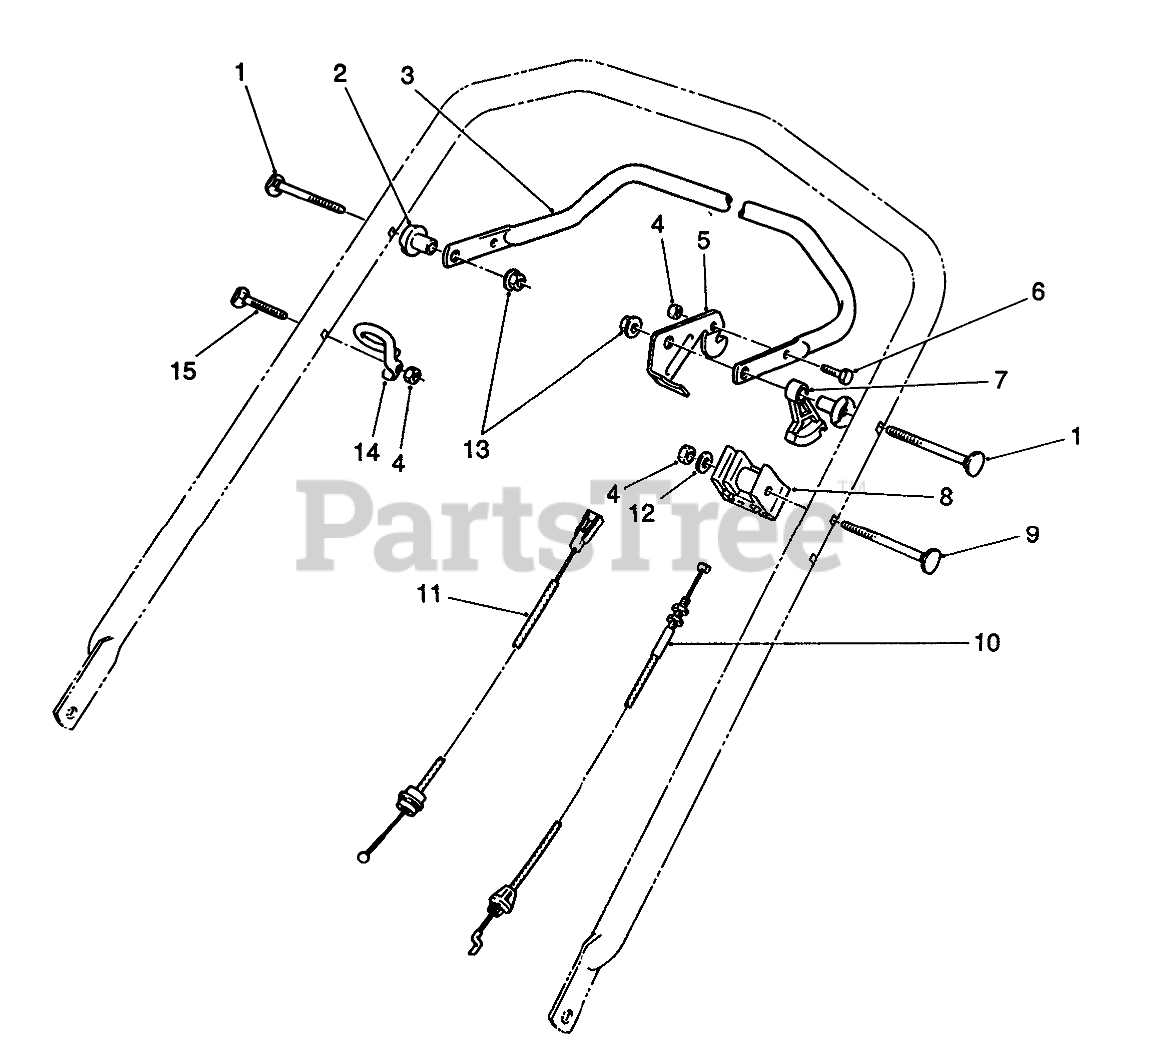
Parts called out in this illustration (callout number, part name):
1	SCREW-HANDLE
2	SPACER-SUPPORT
3	Bar-Control
4	NUT-LOCK, NI
5	LEVER-CONTROL
6	SCREW-HH
7	LEVER-TRACTION
8	SUPPORT-CABLE
9	SCREW-HANDLE
10	TRACTION CABLE
11	BRAKE CABLE
12	WASHER-FLAT
13	NUT-LOCK, NI
14	GUIDE-ROPE
15	Screw-Handle
